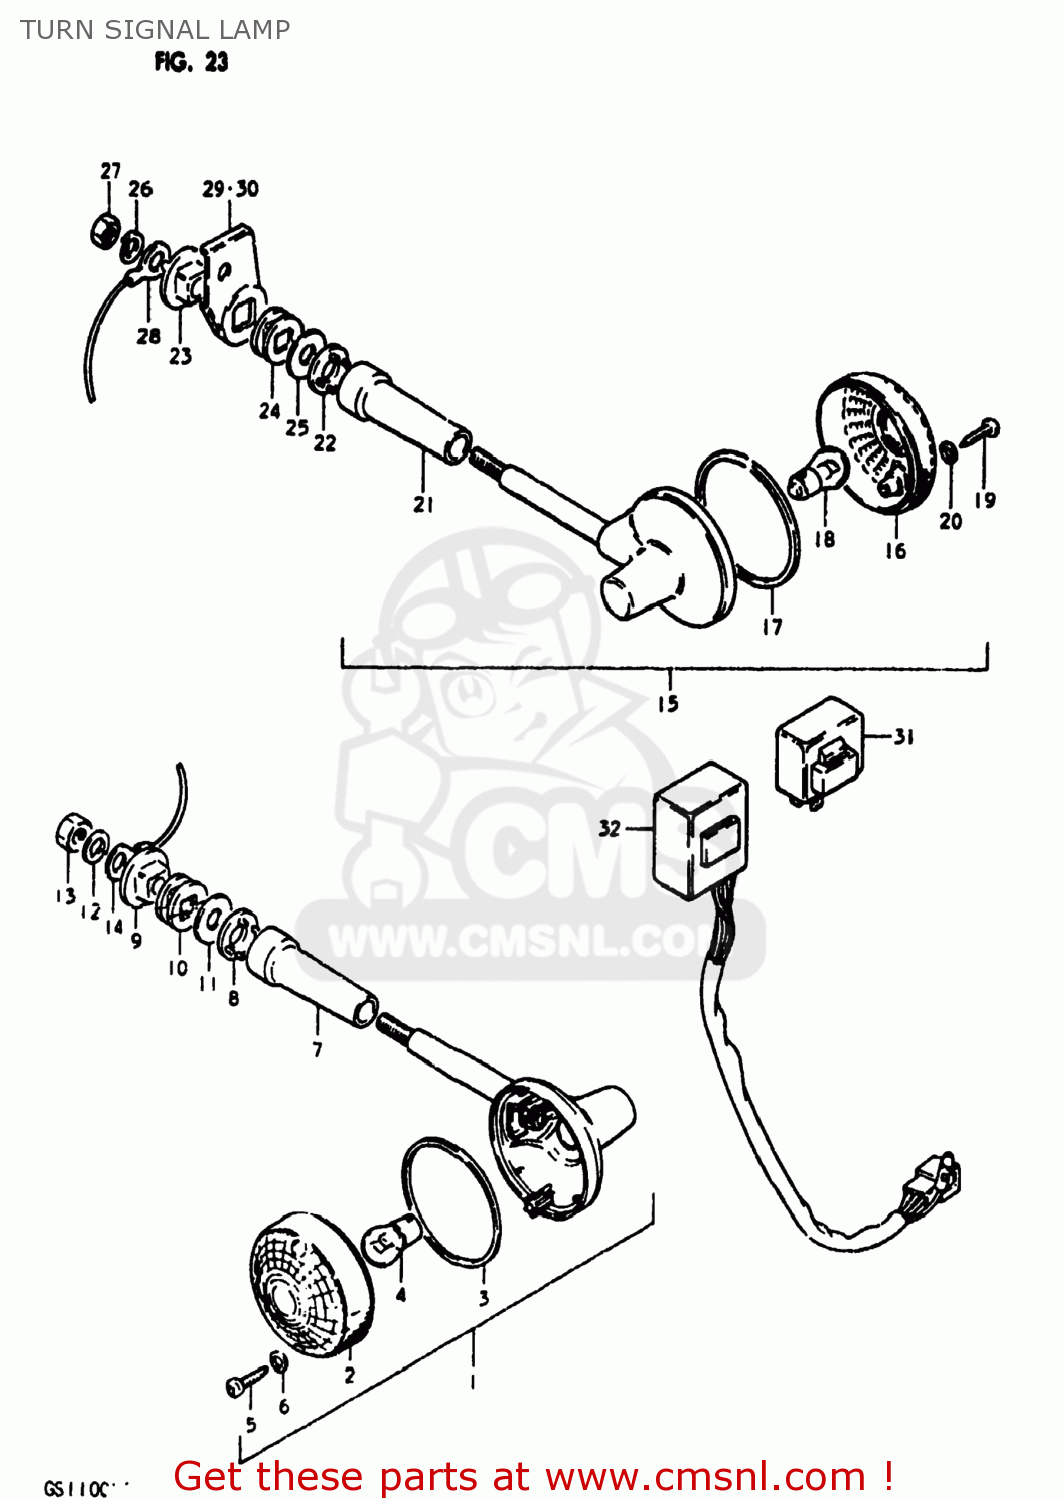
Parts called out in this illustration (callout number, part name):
1	LAMP ASSEMBLY,REAR TURN SIGNAL
2	LENS
3	GASKET (NAS)
4	BULB(12V23W,STANLEY,A4577A)
5	SCREW
6	GASKET (NAS)
7	COVER,STAY
8	SPACER
9	SPACER,TURN SIGNAL LAMP
10	CUSHION
11	WASHER (10.5X30X2.3)
12	LOCK WASHER
13	NUT
14	WIRE
15	LAMP ASSEMBLY,REAR TURN SIGNAL
16	LENS
17	GASKET (NAS)
18	BULB(12V23W,STANLEY,A4577A)
19	SCREW
20	GASKET (NAS)
21	COVER,STAY
22	SPACER
23	SPACER,TURN SIGNAL LAMP
24	CUSHION
25	WASHER (10.5X30X2.3)
26	LOCK WASHER
27	NUT
28	WIRE
29	BRACKET,RR TURNSIGNAL LAMP,R
30	BRACKET,RR TURNSIGNAL LAMP,L
31	RELAY,TURN SIGNAL
32	UNIT,TURN SIGNAL CONTROL
